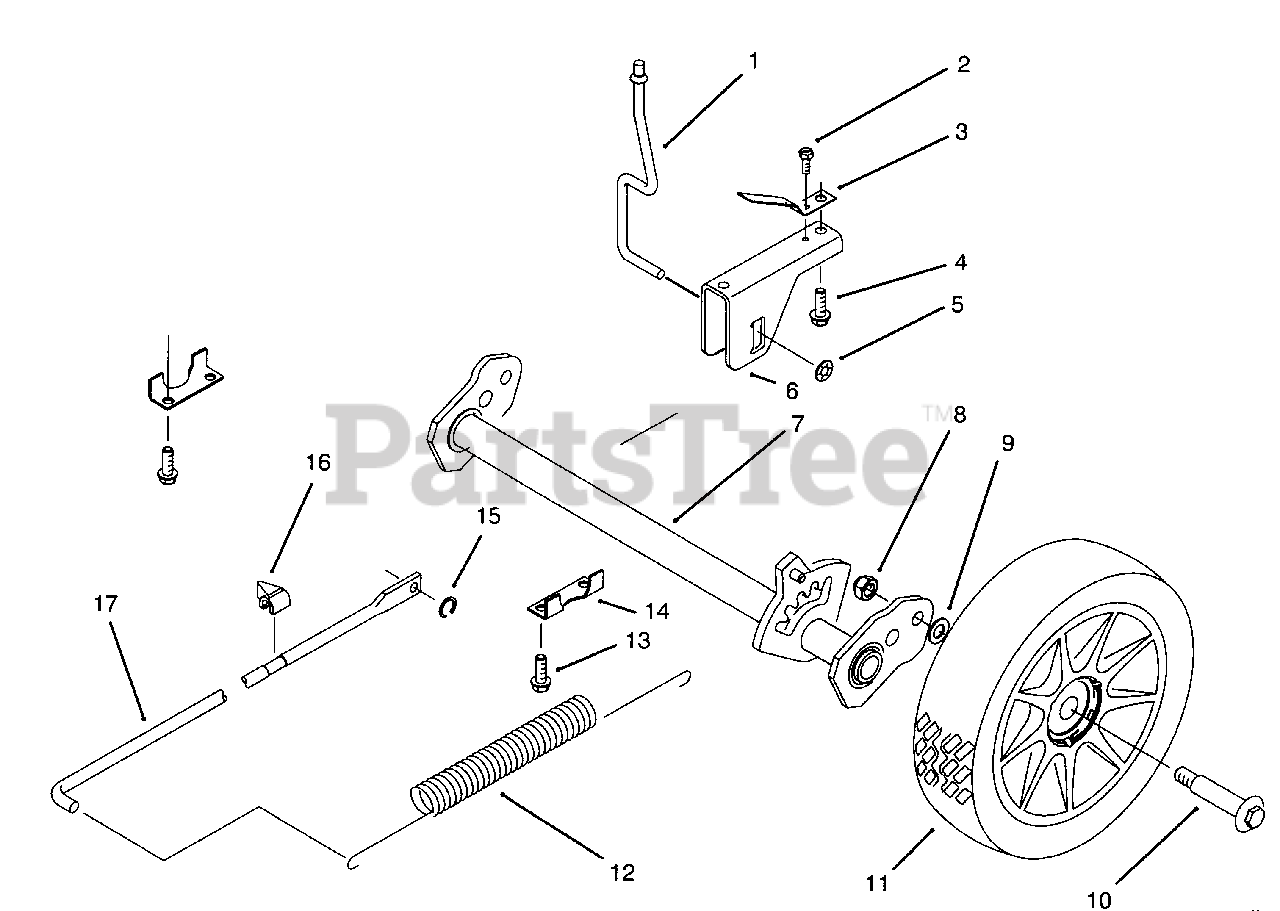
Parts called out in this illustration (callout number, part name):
1	Rod-Trigger
2	Screw-Tapping
3	Spring-Trigger Retainer
6	Saddle-H.O.C.
7	Arm-Pivot
8	Nut-Lock
10	Bolt-Shoulder
11	Wheel & Tire Assembly
12	Spring-Counterbalance
13	Screw-Tapping
14	Plate-Securing Rear
15	Ring-Grip
16	Indicator-H.O.C.
17	Rod-Link
